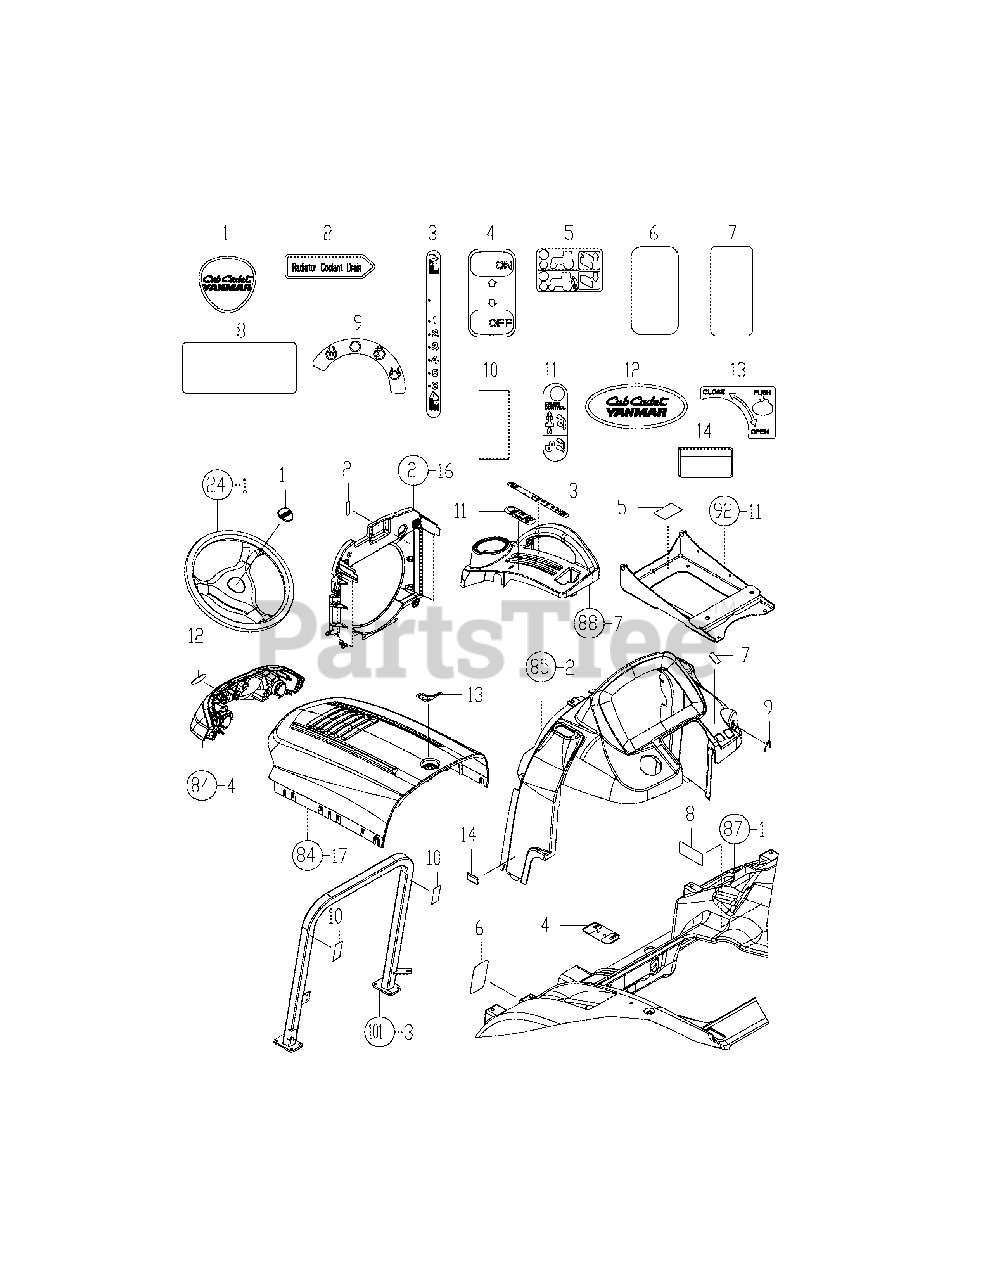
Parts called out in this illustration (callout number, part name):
1	Label, Steering Whell
3	Label, Position
4	Label, Lever 4Wd
5	Label, Lever Valve
6	Label, Difflock
7	Label, Accelerat.Lvr.
7-1	Label, Accelerat.Lvr.
9	Lable, Start Switch
9-1	Lable, Start Switch
10	Tape, Ref.50X115
11	Label, Cruise Ctrl
11-1	Label Lever Guide L
12	Label, Center Logo
13	Label, Hood Open
14	Label, Fuel Oil Noti
